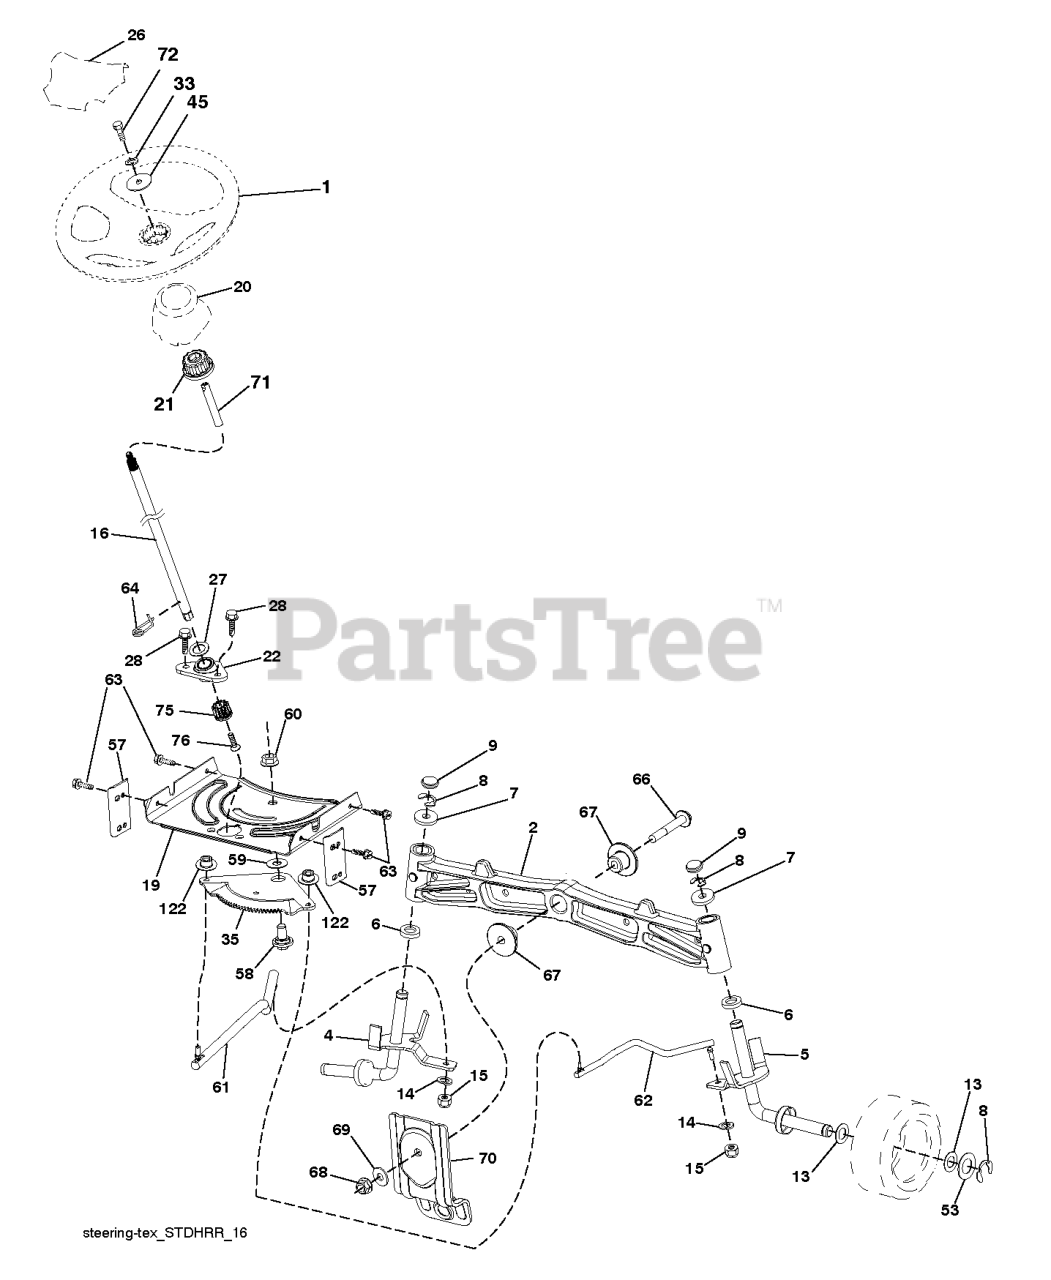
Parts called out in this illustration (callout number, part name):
1	WHEEL.STEER.HUSQ.SR.498.OVMLD
2	AXLE.CAST.IRON
4	SPINDLE.WELDED.LH.15"TEX
5	SPINDLE.WELDED.RH.15"T
6	THRUST WASHER
9	CAP.SPINDLE.BLACK
14	SLW 3/8 STD
15	NUT CROWNLOCK 3/8-24
16	3 HIGH.SHAFT-ZINC.PLATED
19	PLATE.STEER.DDL.NLT/NG
20	STEERING.BOOT.HUSQ.LT
21	ADAPTER, WHEEL STNG..
22	BEARING.SHAFT.STEER.LOWER.625
26	INSERT.CAP.WHL.STRG.HUSQ.PREM
27	WASHER LT
28	SCREW, 3/8-16X3/4
33	WASHER.LOCK.HVY.HLCL.SPR.5/16
35	GEAR.SECTOR.PLATE.DDL.
45	WASHER.11/32
53	WASHER.HARDENED
57	BRACKET.UPSTOP.TEX
58	BOLT.SHOULDER.SECTOR.P
59	WASHER.THURST.SECTOR.S
60	NUT FLANGE LOCK 5/8-11
61	LINK.ASM.DRAG.ADJUST.LH.PLATED
62	LINK.ASM.DRAG.ADJUST.RH.PLATED
63	SCREW
64	RETAINER.CLIP.SPRING.S
66	BOLT HEX FGHD 7/16-14 X 3 SERR
67	BUSHING.PM.FRONT AXLE
68	NUT.LOCK.FLANGE.7/16
69	WASHER.1.5X.505X.118
70	BRACKET.FRT.DECK.SUSP.RR.MT431
71	SHAFT.EXTEN.STRG.SPLINE
72	BOLT 5/16-18 X 4 W/PATCH
75	PINION.ZINC PLATED
76	SCREW HEAD SOCKET LRVB
122	CAP.GEAR.SECTOR.TEX
